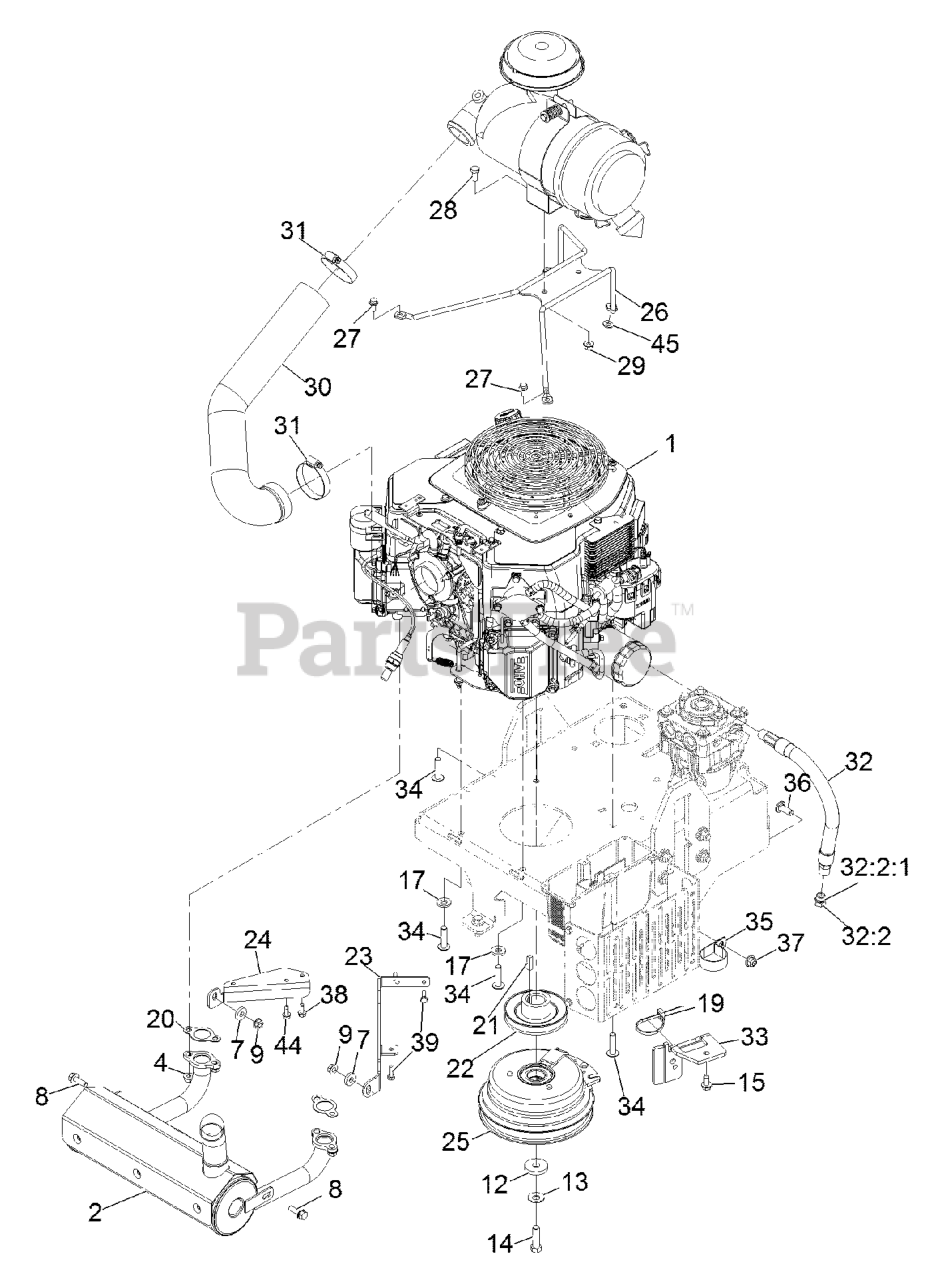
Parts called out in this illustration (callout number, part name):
1	Engine, Kohler
4	NUT-FLANGE
8	SCREW-HHF
12	WASHER
13	WASHER-SPRING
14	SCREW-HH
15	Screw-HWH 5/16-18 X 3/4 Tf
17	WASHER-BELLEVILLE
19	TIE-CABLE
20	GASKET-EXHAUST
23	MOUNT, MUFFLER-LT
24	MOUNT, MUFFLER-RT
25	CLUTCH-200 FT-LB, 1.125 B
26	MOUNT-CLEANER, AIR
27	SCREW-HHF
28	SCREW-HH
29	NUT-HF, NI
30	HOSE-INTAKE, AIR
31	CLAMP-HOSE
32	OIL DRAIN HOSE ASM
32:2	PLUG-HH
32:2:1	O-RING
33	BRACKET-ANCHOR, CLUTCH
34	SCREW-BHTF
35	CLAMP-R
36	SCREW-CARR
37	NUT-HF, NI
38	SCREW-HWHTF
39	SCREW-HH M6-1 X 20Mm W/Patch
44	SCREW-HWHTF
45	WASHER-PLAIN
